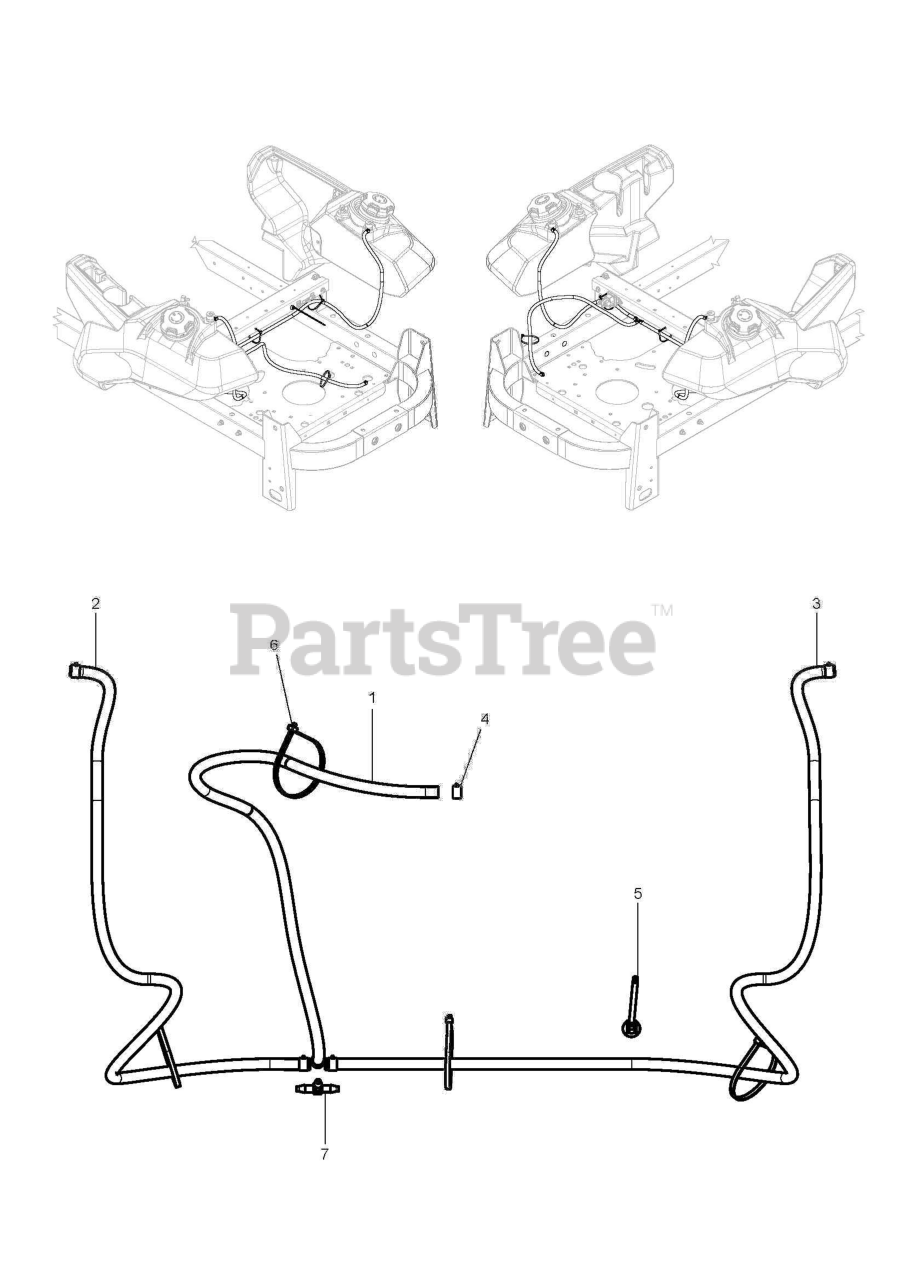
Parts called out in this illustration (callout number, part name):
1	HOSE.3/16".VAPOR.LINE.26"LGTH
2	HOSE.3/16".VAPOR.LINE.26"LGTH
3	HOSE 3/16" VAPOR LINE 41" LENG
4	CLAMP, HOSE
5	CABLE.TIE.6".FIRTREE.PZ.REFRES
6	TIE, PLASTIC
7	TEE, FUEL LINE 3/16"
